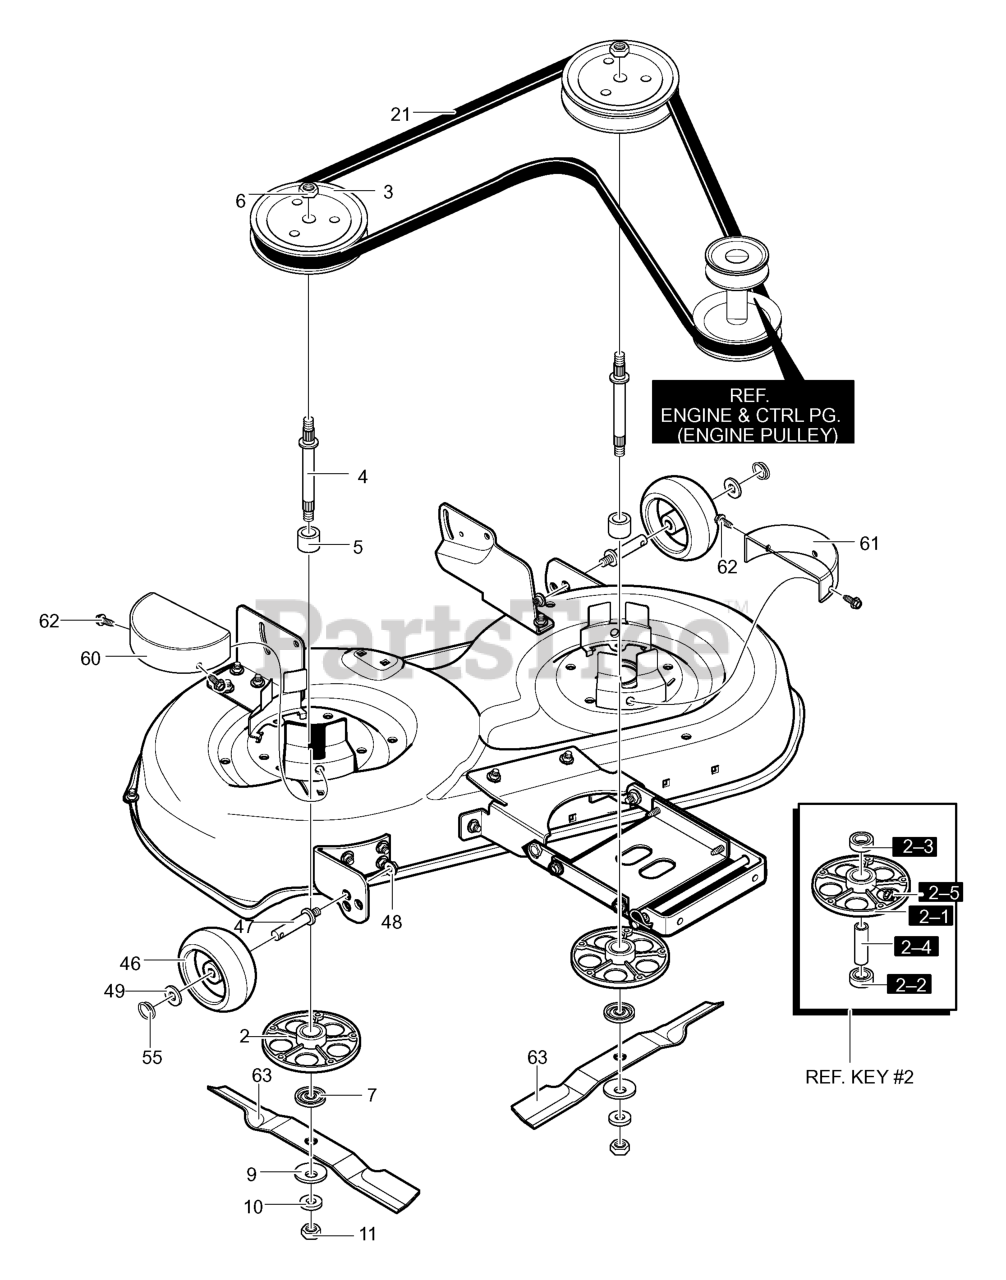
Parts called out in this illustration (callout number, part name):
2	Jackshaft Assembly
2-1	Jackshaft Housing
2-2	Bearing, Lower Jackshaft
2-3	Bearing, Upper Jackshaft
2-4	Spacer, .625x.875x1.71
2-5	Zerk, Grease
3	Pulley, Split
4	Jackshaft
5	Spacer, .625x.875x1.85
6	Nut, 9/16-18
7	Adapter, Deck/Blade
11	Nut, .56-18 Regular
21	Belt, 42" Deck
46	Gauge Wheel
47	Bolt, SPSH 3/8-16
48	Nut, 3/8-16 Wdfllk
49	Flat washer
55	Circle Pin
60	GUARD, Belt R.H.
61	GUARD, Pulley L.H.
62	Screw, 1/4-20x.63
63	Blade, 42" Low Lift
